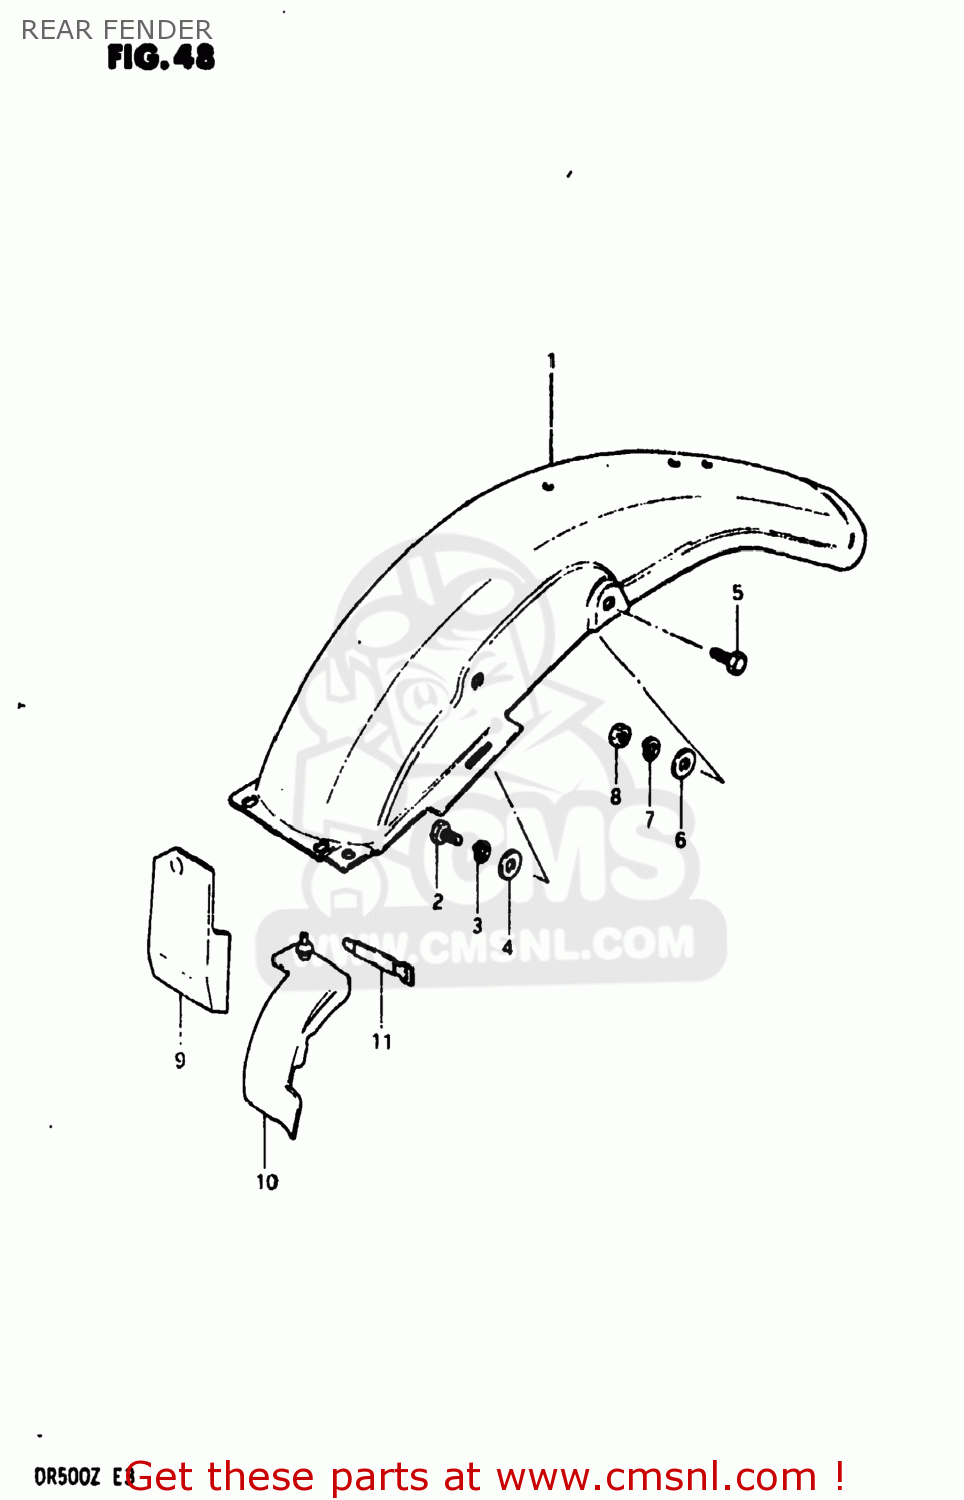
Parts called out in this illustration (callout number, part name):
1	FENDER,REAR
2	BOLT
3	LOCK WASHER
4	WASHER (8.2X20X1.6)
5	BOLT
6	WASHER (8.2X20X1.6)
7	WASHER,LOCK,8.
8	NUT
9	MUD GUARD,REAR FENDER
10	MUD GUARD,REAR FENDER
11	CLAMP L:110
